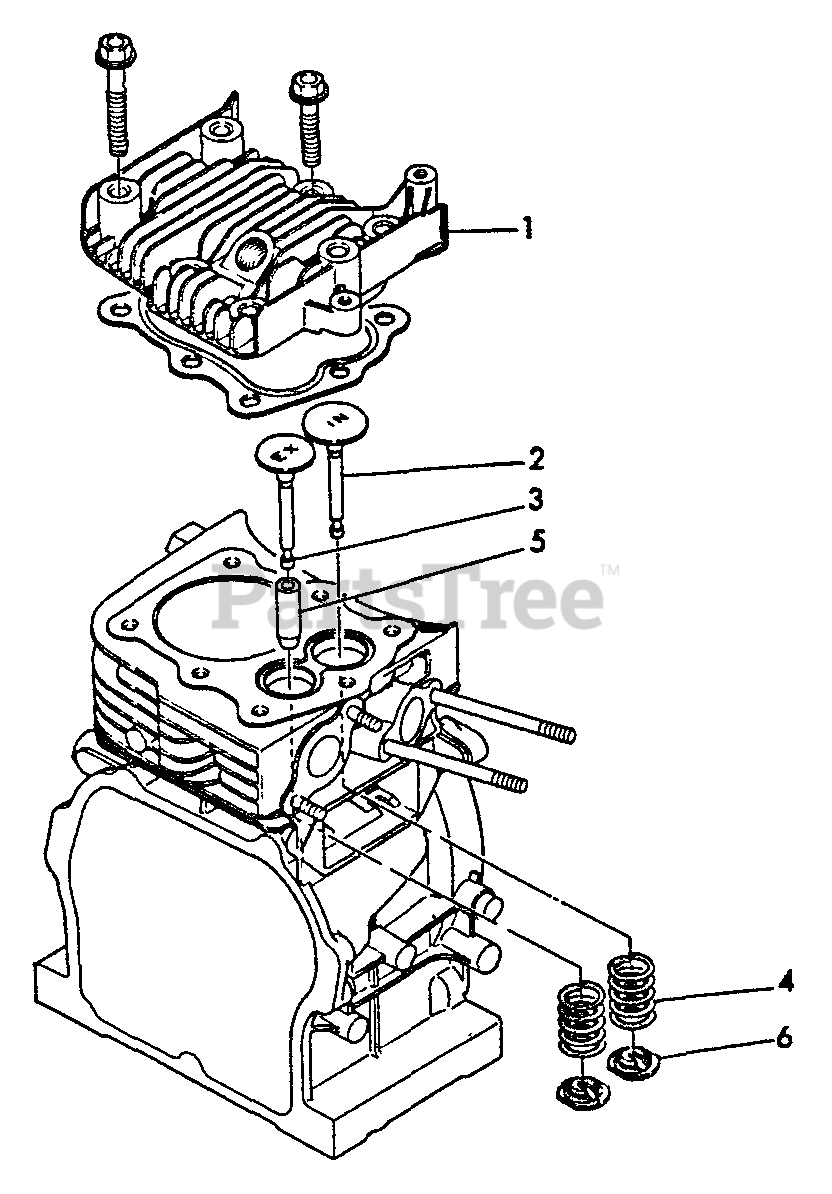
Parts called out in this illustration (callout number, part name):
1	HEAD, CYLINDER
2	VALVE
3	VALVE, EXHAUST
4	SPRING, VALVE
5	GUIDE, VALVE - EXHAUST
6	RETAINER, SPRING
